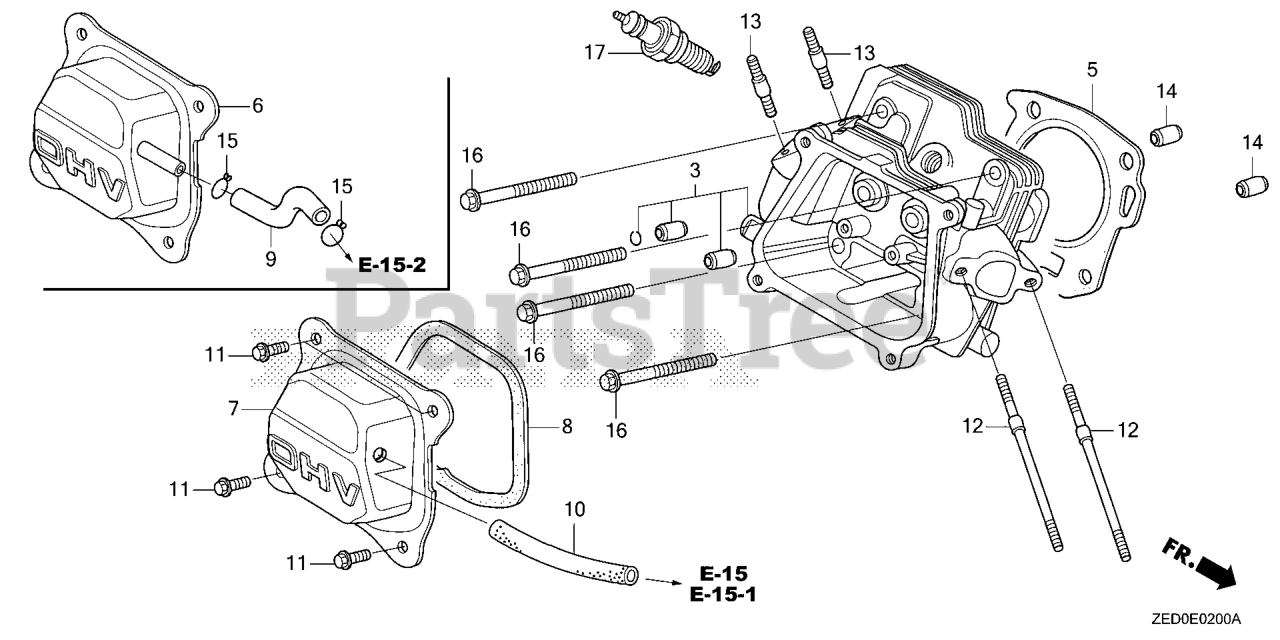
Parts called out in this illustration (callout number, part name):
1	GUIDE, VALVE (OVER SIZE) Use from Engine SN 6324986.
2	GUIDE, EX. VALVE (OS)
3	CYLINDER HEAD
4	CLIP, VALVE GUIDE Use from Engine SN 1231803.
5	GASKET, CYLINDER HEAD (NIPPON LEAKLESS)
7	COVER, HEAD
8	GASKET, HEAD COVER (NINGBO SIL GASKET)
8	GASKET, CYLINDER HEAD COVER
10	TUBE, BREATHER
11	BOLT, FLANGE (6X12) (CT200)
12	BOLT, STUD (6X112)
13	BOLT, STUD (8X32)
14	PIN A, DOWEL (10X16)
16	BOLT, FLANGE (8X60)
17	SPARK PLUG (BPR5ES) (NGK)
17	SPARK PLUG (W16EPR-U) (DENSO)
17	SPARK PLUG (BPR6ES) (NGK)
17	SPARK PLUG (W20EPR-U) (DENSO)
